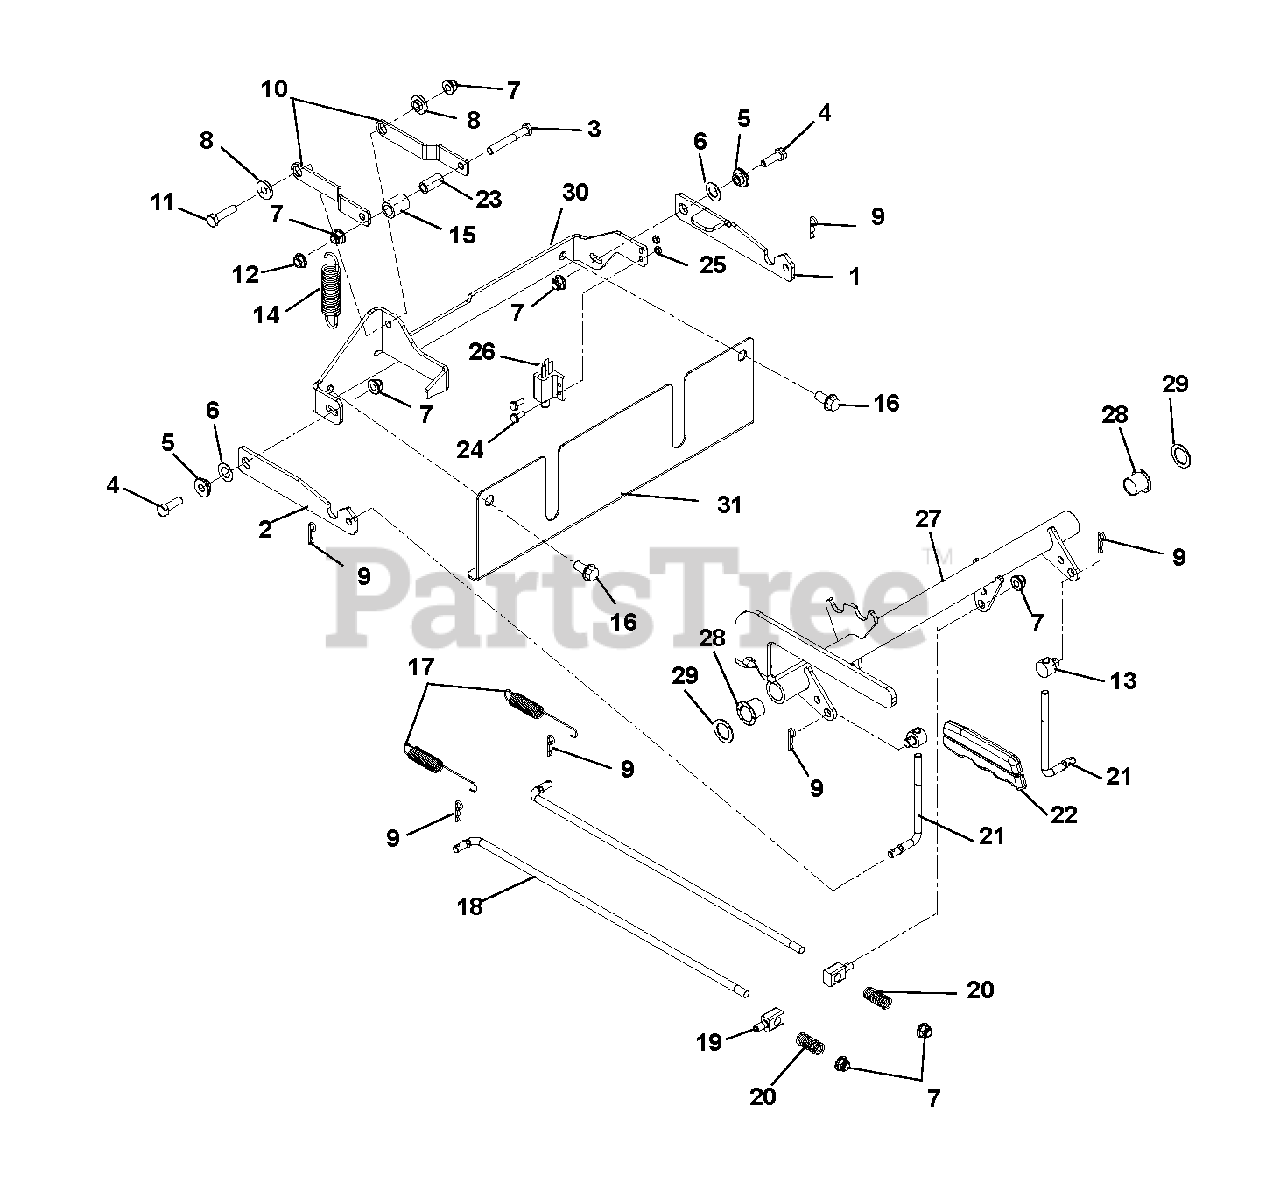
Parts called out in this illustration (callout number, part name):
1	Link, Brake Interlock
2	Interlock, Brake
3	Bolt, Hex .31-18 x 2.25 Grade 5
4	Bolt, Hex .31-18 x 1.00 Grade 5
5	Bushing, Flange .312 x .500 x .344 x .880
6	Washer, Flat Steel .505 x .875 x .024
7	Nut, Flange Nyloc 5/16-18
8	Shoulder Spacer
9	Pin, Hair Internal .08 x .18 x 1.18
10	Arm, Brake Cam
11	Bolt, Hex .31-18 x 1.25 Grade 5
12	Nut, Locking Top Flange .31-18
13	Trunnion, Brake
14	Spring, Tension .105 x .812 x 3.88
15	Roller, Cam Lock
16	Screw, Tapping .38-16 x .75 Hex Washer Head
17	Spring, Tension .056 x .60 x 4.40
18	Rod, Park Brake
19	Pin, Pivot
20	Spring, Compression
21	Link, Interlock Brake
22	Grip, Park Brake
24	Screw, Machine 10-24 x .50 Hex Washer Head
25	Nut, Locking Nylon 10-24 with Insert
26	Switch, Double Pole
27	Weldment, Brake Shaft
28	Bushing, IGLIDE Clip
29	Washer, Flat Steel .754 x 1.125 x .062
30	Bracket, Brake Mounting
31	Bracket, Lower Finger Guard
